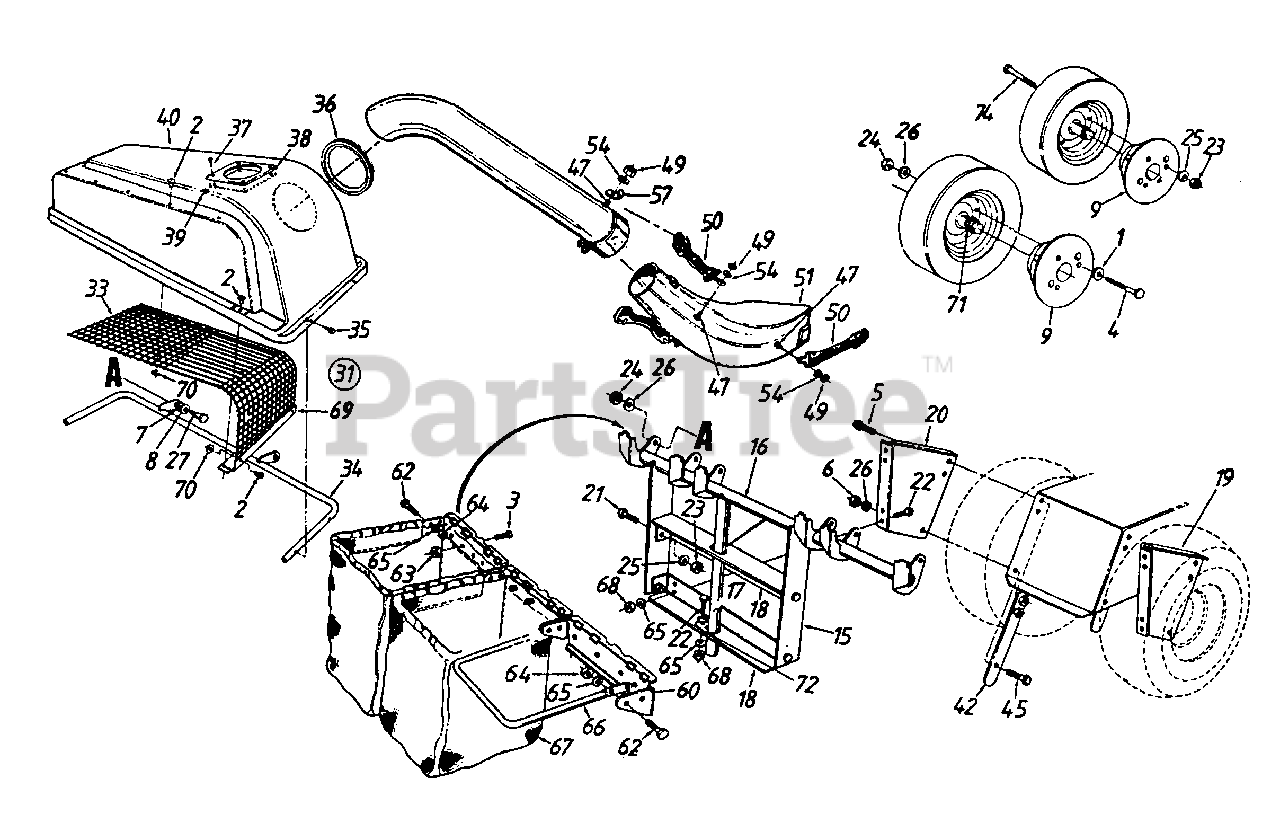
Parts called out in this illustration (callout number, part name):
1	Fl-Wash. .385" I.D.
2	Pop Rivet
3	Truss Mach. Scr. #10-24 x .38"
4	Hex Bolt 3/8-16 x 4.5" Lg.
5	Hex Wash. Hd. Tap Scr. 5/16-18 x .62"
6	Hex Nut 3/8-24 Thd.
7	Bell-Wash. .515" I.D.
8	Fl-Wash. .510" I.D.
18	Catcher Latch and Support Brkt.
22	Hex Bolt 1/4-20 x .62" Lg. - Grade 5
23	Hex Nut 5/16-18 Thd.
24	Hex Nut 3/8-16 Thd.
25	L-Wash. 5/16" I.D.
26	L-Wash. 3/8" I.D.
27	Shld. Bolt 3/8-16 x .500" Dia.
31	Grass Catcher Cover Ass'y. Comp.
33	Screen
36	Tube Seal
37	Truss Mach. B-Tap Scr. #10 x .5" Lg.
38	Plastic Plate
39	Speed Nut
40	Grass Catcher Cover
47	Hex Bolt 1/4-20 x .50" Lg.
49	Hex Ins. L-Nut 1/4-20 Thd.
50	Retainer Strap Ass'y.
51	Discharge Chute
54	L-Wash. .270" I.D. x .57" O.D.
57	Retainer Hook Brkt.
62	Hex Bolt 1/4-28 x .75" Lg.
63	Hex Sems Nut #10-24 Thd.
64	Hex Nut 1/4-28 Thd.
65	L-Wash. 1/4" I.D.
66	Catcher Bag Frame
67	Grass Catcher Bag
68	Hex Nut 1/4-20 Thd.
71	Foam Strip 1-1/8" x 1-1/2" x 3/8"
74	Hex Bolt 5/16-18 x 4" Lg.
